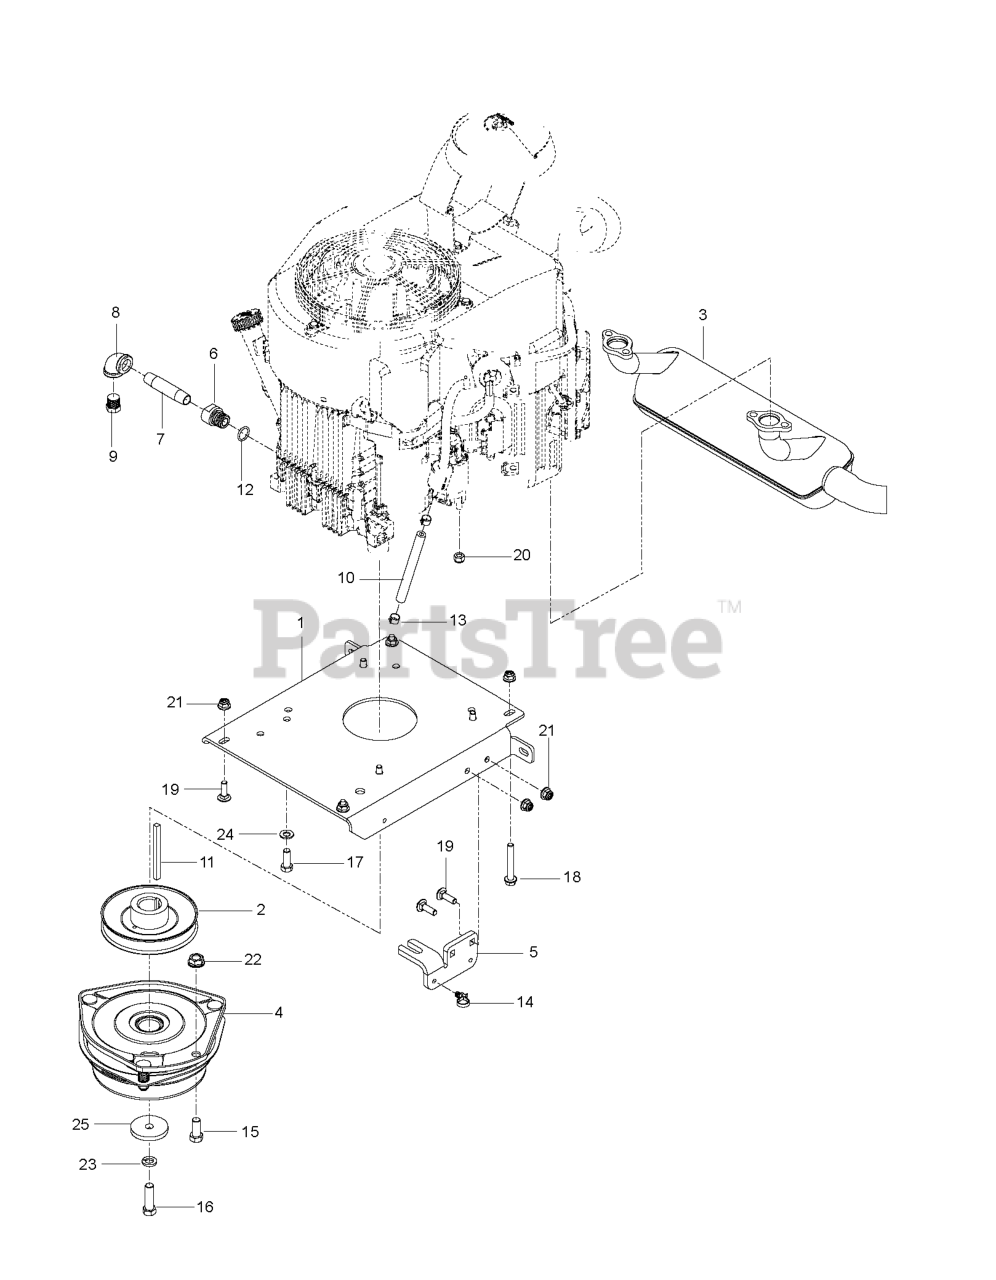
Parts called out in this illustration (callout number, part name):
5	SCREW EHHM
10	IGNITION SWITCH
11	IGNITION SWITCH
13	IGNITION KEY
22	%BRAKER
27	SPACER TUBE
28	SCREW
29	WASHER BRB 8.4X17
30	RP MICRO SWITCH
